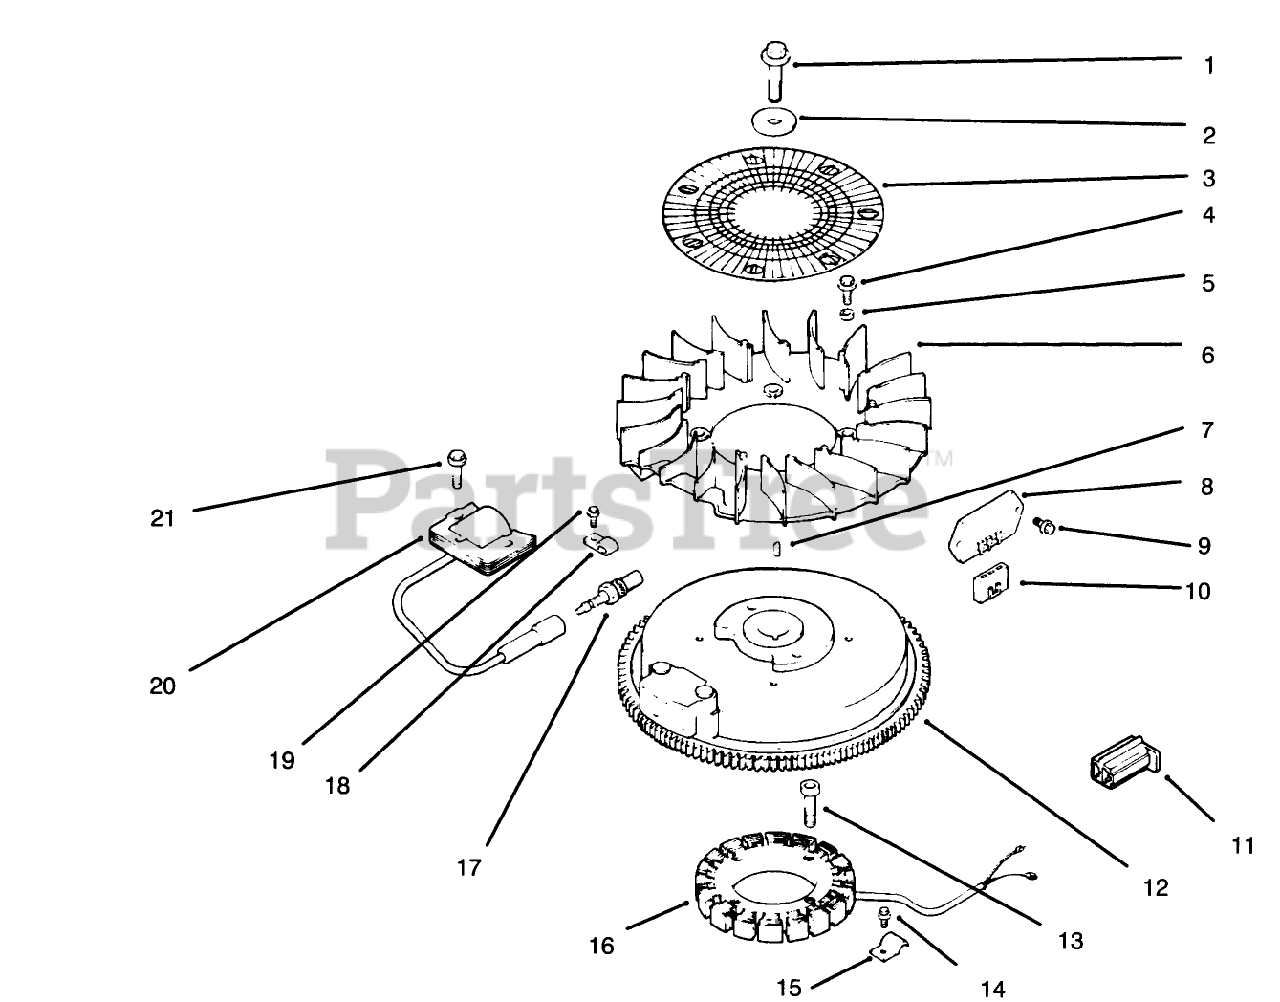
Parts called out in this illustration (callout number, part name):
3	Screen-Grass
4	Screw-Fan
5	Spacer-Fan
6	Fan (Only On: 72042, 72063, 72062, 72043)
8	Rectifier-Unregulator
10	Connector
11	Connector
12	Flywheel
15	Clip-Stator Harness (Only On: 72042, 72063, 72062, 72043)
16	Stator 15 amp.
17	Spark Plug
20	Module-Ignition (Only On: 72042,72043,72062,72063)
